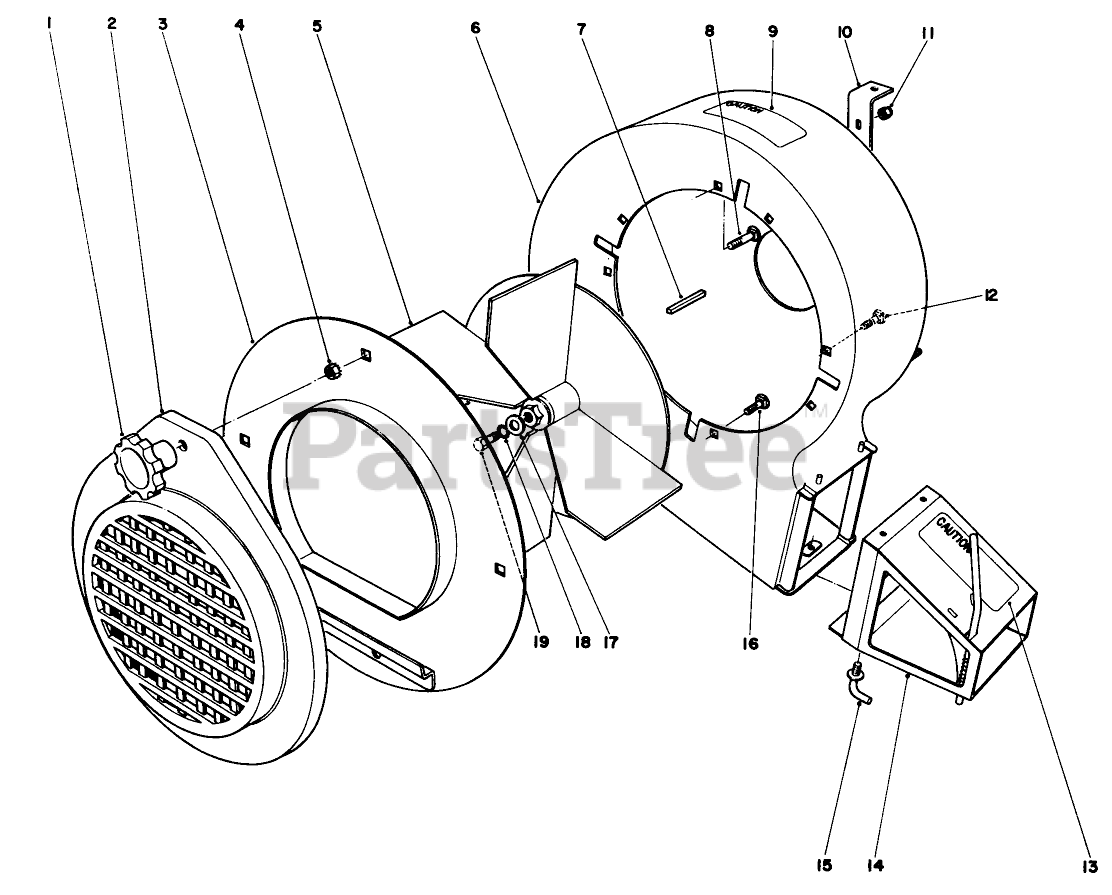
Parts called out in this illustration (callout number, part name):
2	INTAKE-BLOWER
4	NUT-KEPS
7	KEY-SQUARE
8	SCREW-CARR
11	NUT-LOCK, CONE
12	BOLT-CARR
15	1/4 - 20 3/4 WING SCR
16	SCREW-CARR
17	WASHER-FLAT
18	Lockwasher
